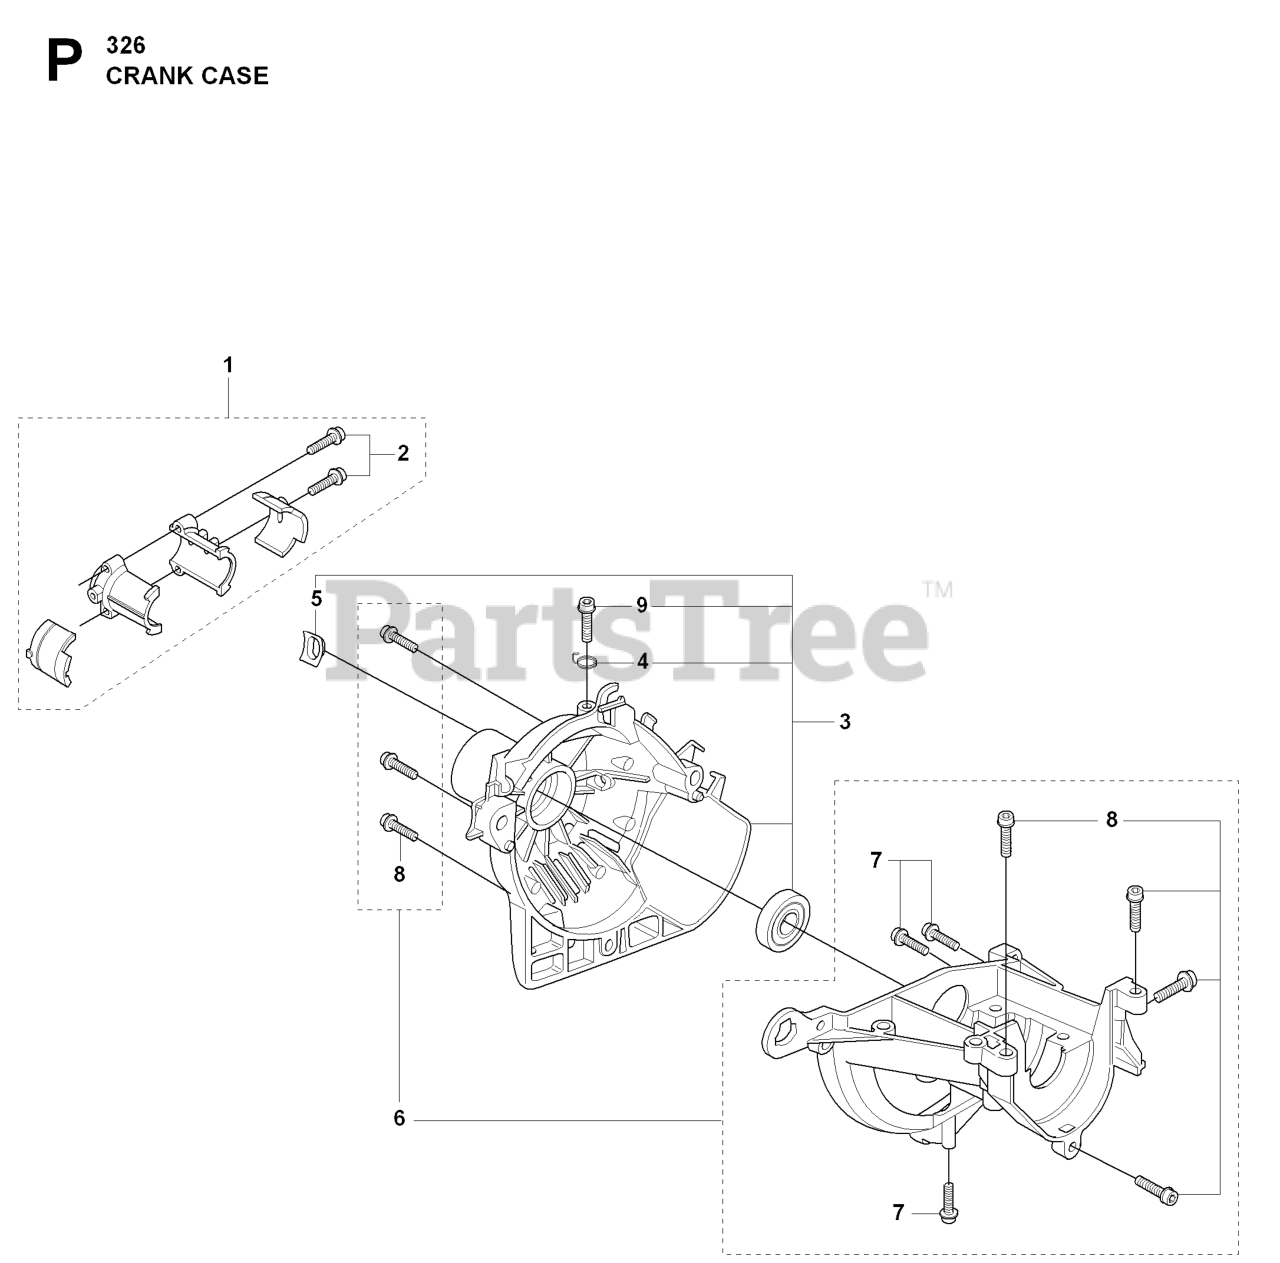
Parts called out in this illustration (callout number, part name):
1	COMPRESION SLEEVE/ISOLATOR SET
3	RP CLUTCH COVER
5	PROTECTION PLATE
